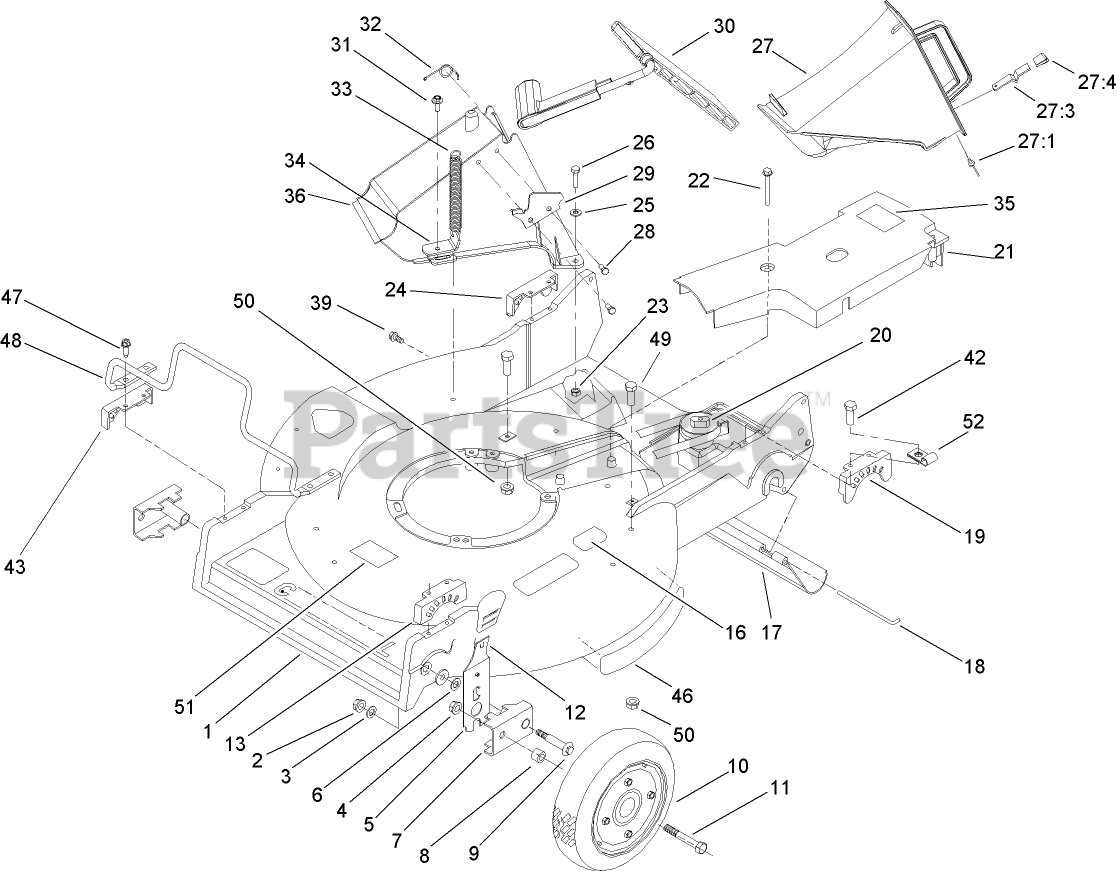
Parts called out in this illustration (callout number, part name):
1	HOUSING ASM
2	NUT-LOCK
3	WASHER
4	NUT-LOCK, CONE
6	WASHER-THRUST
7	ARM-PIVOT, FRONT
8	SPACER-WHEEL
11	SCREW-HH
12	KNOB-HOC
13	QUADRANT-FRONT, LH
16	DECAL-STD, SAFETY
18	ROD-SHIELD
19	QUADRANT-REAR, LH
21	COVER-BELT
22	SCREW-HWH
23	NUT-LOCK, NI
24	QUADRANT-REAR, RH
25	WASHER-FLAT
26	SCREW-HH
27	DISCHARGE PLUG ASM
27:1	RIVET-HEAD, FLAT
27:3	LATCH-PLUG, DISCHARGE
27:4	GRIP-LATCH
28	SCREW-PLASTITE
29	LATCH-PLATE
30	DISCHARGE DOOR ASM
31	SCREW-HWH
32	RETAINER-DOOR
33	SPRING-DOOR
34	BRACKET-SPRING
36	TUNNEL-DISCHARGE
39	SCREW AND WASHER ASM
42	SCREW-HWHTF
43	QUADRANT-FRONT, RH
47	SCREW-HWHTF
48	GUARD-ENGINE
49	SCREW-HH
50	NUT-LOCK, NI
51	DECAL-BLADE
52	CLIP-CLOSED, INSULATED
